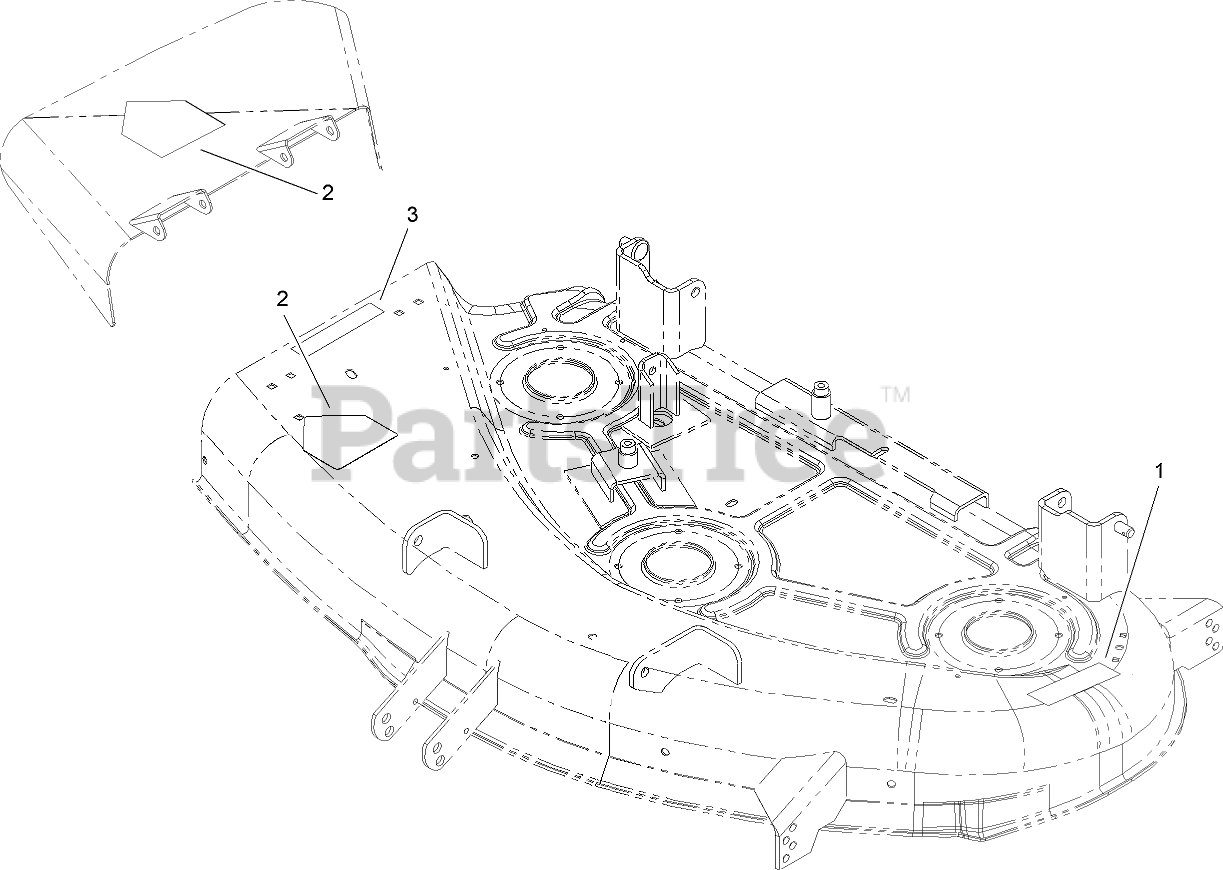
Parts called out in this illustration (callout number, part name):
1	DECAL-DANGER
2	DECAL-DANGER
3	DECAL-DANGER
